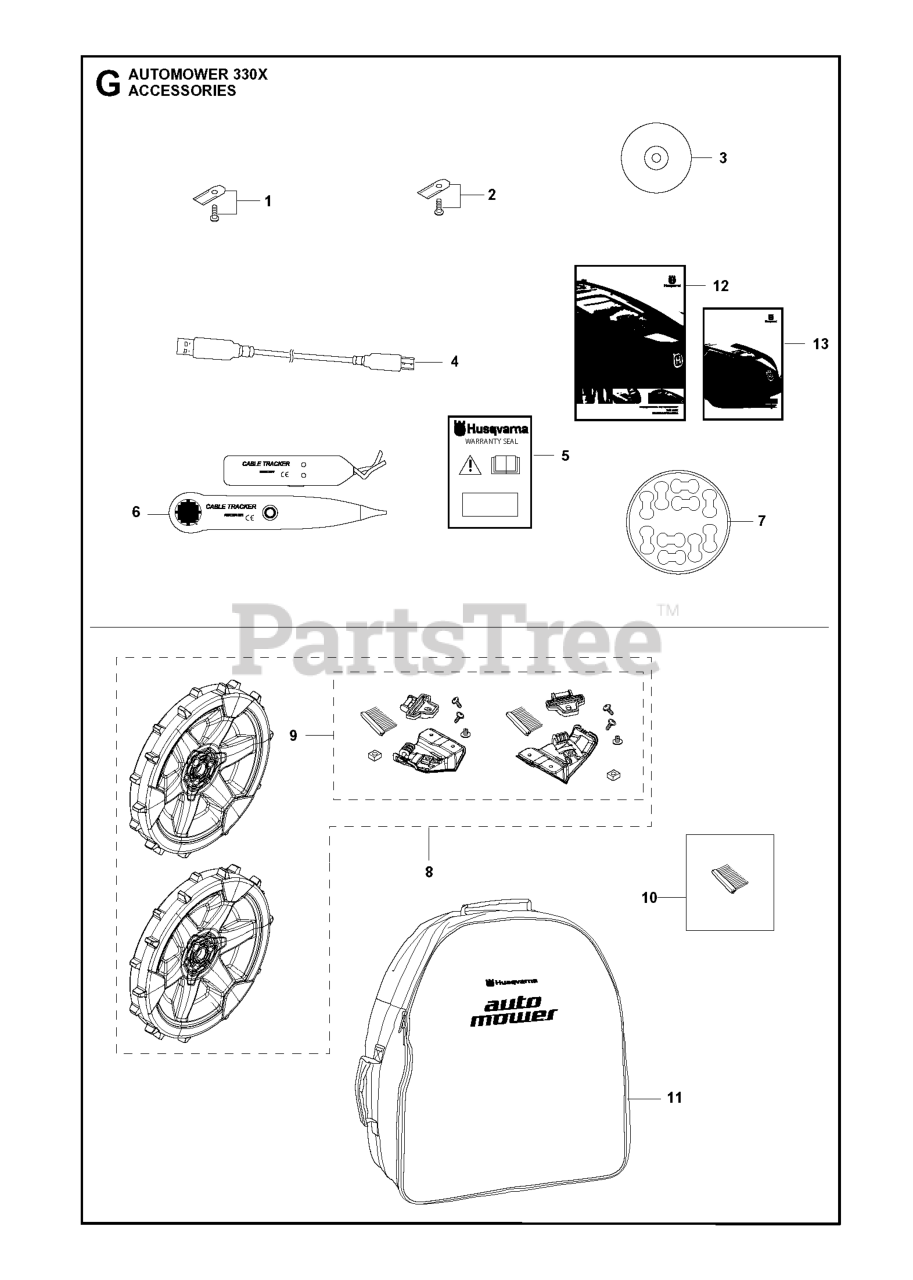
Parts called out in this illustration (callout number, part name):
1	BLADE - BULK PACK 500 PCS
1	BLADE
1	BLADE KIT
1	BLADE - 30 PCS
2	BLADE 300PCS -SINGLE HOLE THIC
2	BLADE 9PCS EXTRA THICK
2	BLADE BLADE KIT INCL PACKAGING
2	BLADE CARBON STEEL, THICK BLAD
5	LABEL WARRANTY SEAL KIT 10 PK
5	LABEL WARRANTY SEAL DEALER
6	TEST EQUIPMENT
